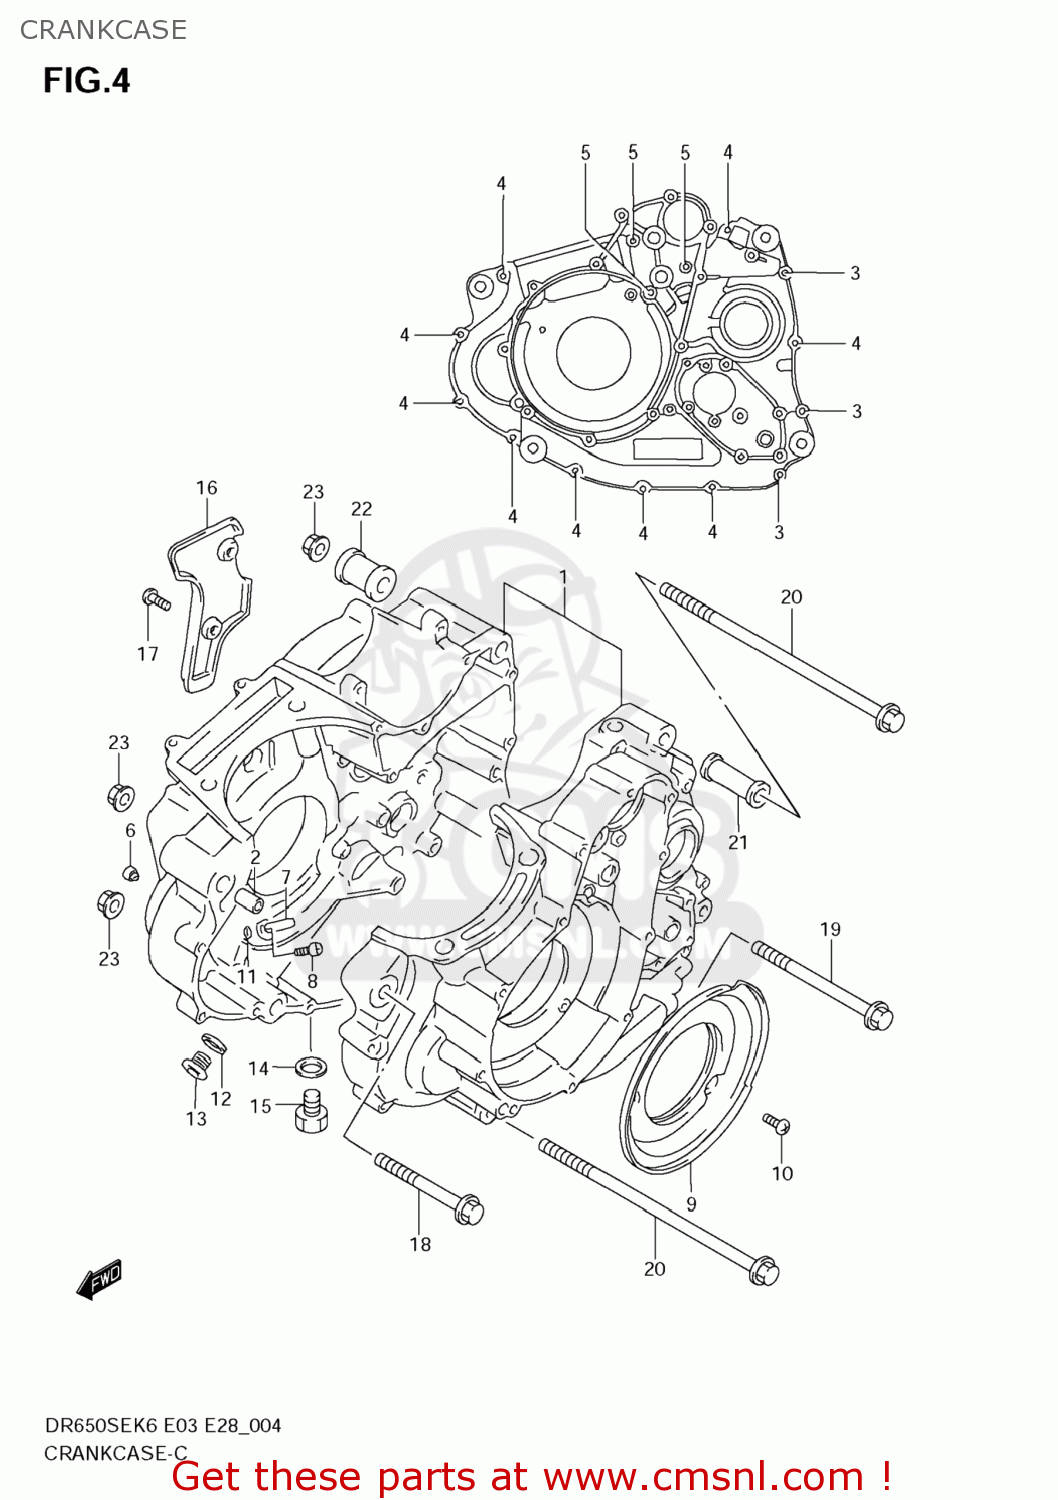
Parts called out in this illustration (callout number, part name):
1	CRANKCASE SET
2	PIN
3	BOLT(6X60)
4	BOLT(6X40)
5	BOLT
6	JET,OIL GALLERY
7	JET,PISTON COOLING
8	BOLT(6X12)
9	SEPARATOR,CRANKCASE OIL
10	SCREW
11	O RING(D:1.2,ID:4)
12	GASKET(13.8X18.8X4.8) (NAS)
13	PLUG,14X12
14	GASKET(13.8X18.8X4.8) (NAS)
15	PLUG(14X12)
16	COVER,BREATHER
17	SCREW
18	BOLT(10X100)
19	BOLT(10X130)
20	BOLT(10X235)
21	SPACER,ENGINE MOUNT(L:65)
22	SPACER,ENGINE MOUNT(L27)
23	NUT
